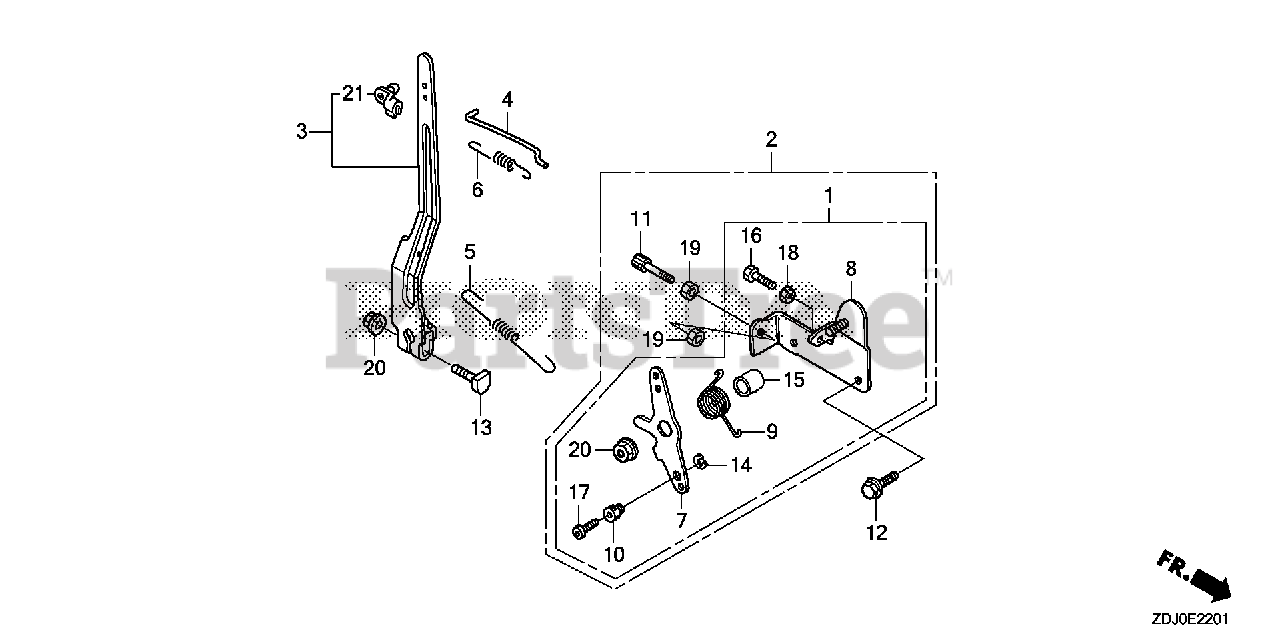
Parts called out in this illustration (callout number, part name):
1	CONTROL ASSY.
3	ARM, GOVERNOR
4	ROD, GOVERNOR
5	SPRING, GOVERNOR
6	SPRING, THROTTLE RETURN
7	LEVER, CONTROL (REMOTE)
8	BASE, CONTROL
9	SPRING, RETURN
10	HOLDER, WIRE
12	BOLT, FLANGE (6X14)
13	BOLT, GOVERNOR ARM
14	CIRCLIP (5MM) Use from Engine SN 2327377.
15	COLLAR, CONTROL LEVER
16	BOLT, HEX. (5X20)
17	SCREW, PAN (4X6)
18	NUT, HEX. (5MM)
20	NUT, FLANGE (6MM)
21	JOINT, ROD
